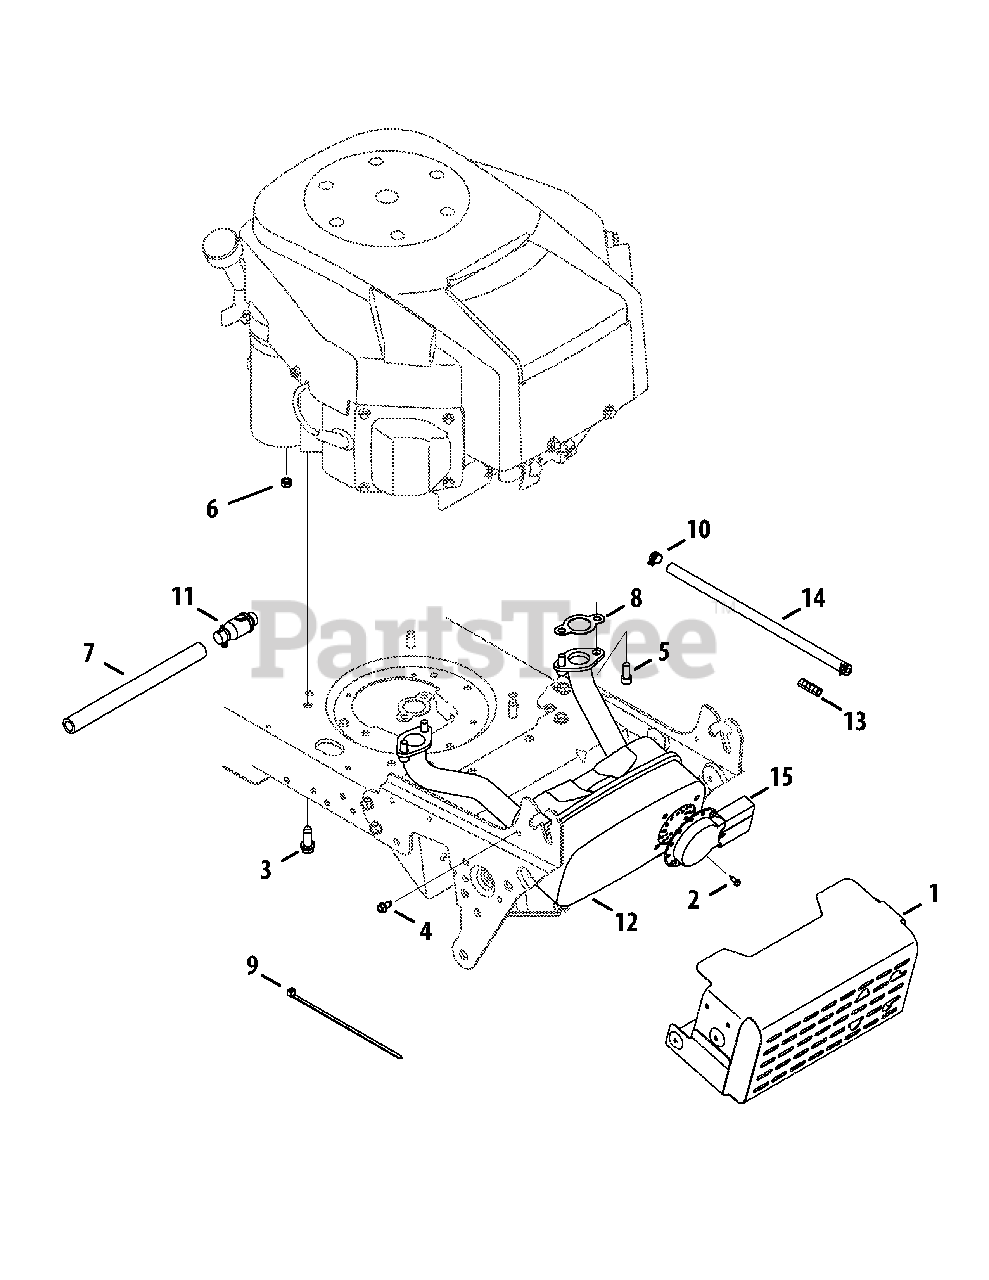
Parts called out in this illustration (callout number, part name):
1	Shield Ass’y, Muffler
2	Screw, Ab, #8-18, 0.500,
3	Screw, Self-tapping, 3/8-16, 1.000,
4	Screw, Self-tapping, 1/4-20, 0.500,
5	Screw, Socket Head, 5/16-18, .750
6	Nut, Sems, 1/4-20
7	Hose, Extension, Oil Drain
8	Gasket, Exhaust, Briggs
9	Cable, Tie, 3/16 x .05 x 7.4
10	Clamp, Hose, .490 Dia.
12	Muffler, Briggs Twin
14	Hose, Fuel, Low Permeation, 1/4
15	Deflector, Muffler, Long
